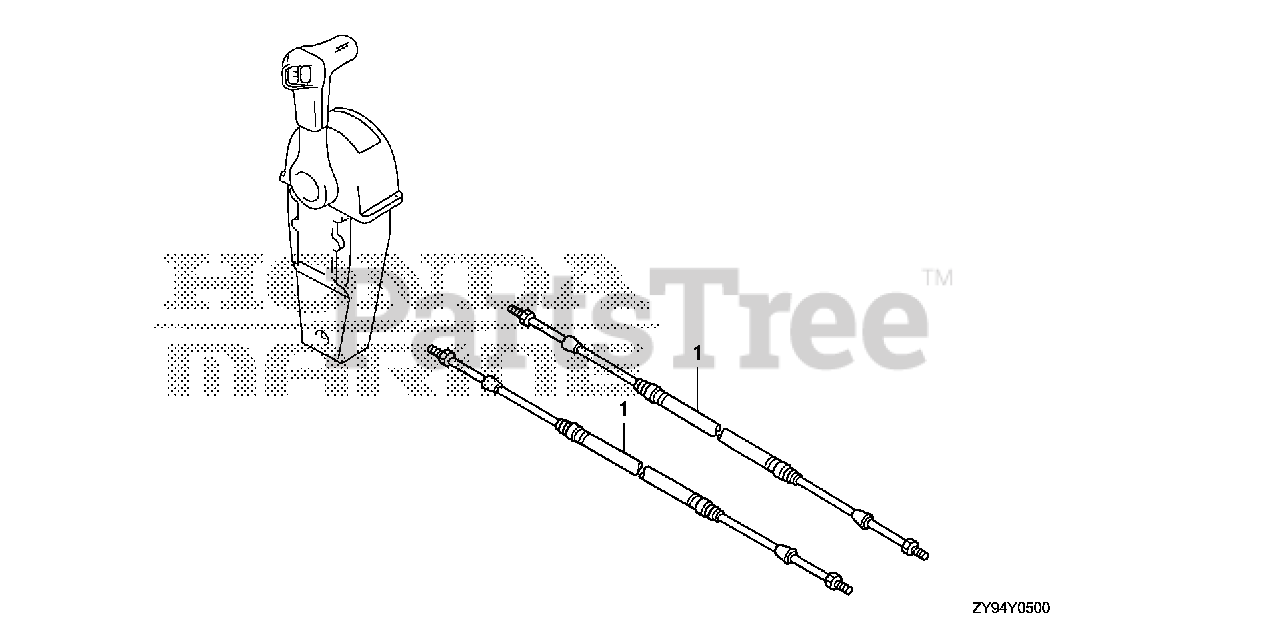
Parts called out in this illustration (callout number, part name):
1	CABLE, REMOTE CONTROL (10'') (LOW FRICTION)
1	CABLE ASSY., PUSH-PULL (33C-5FT)
1	CABLE, REMOTE CONTROL (11'') (LOW FRICTION)
1	CABLE ASSY., PUSH-PULL (33C-6FT)
1	CABLE, REMOTE CONTROL (12'') (LOW FRICTION)
1	CABLE ASSY., PUSH-PULL (33C-7FT)
1	CABLE, REMOTE CONTROL (13'') (LOW FRICTION)
1	CABLE ASSY., PUSH-PULL (33C-8FT)
1	CABLE, REMOTE CONTROL (14'') (LOW FRICTION)
1	CABLE ASSY., PUSH-PULL (33C-9F T)
1	CABLE, REMOTE CONTROL (15'') (LOW FRICTION)
1	CABLE ASSY., PUSH-PULL (33C-10FT)
1	CABLE, REMOTE CONTROL (16'') (LOW FRICTION) (NOT AVAILABLE)
1	CABLE ASSY., PUSH-PULL (33C-11FT)
1	CABLE, REMOTE CONTROL (17'') (LOW FRICTION)
1	CABLE ASSY., PUSH-PULL (33C-12 FT)
1	CABLE, REMOTE CONTROL (18') (LOW FRICTION) (NOT AVAILABLE)
1	CABLE ASSY., PUSH-PULL (33C-13 FT)
1	CABLE, REMOTE CONTROL (1 9'') (LOW FRICTION)
1	CABLE ASSY., PUSH-PULL (33C-14FT)
1	CABLE, REMOTE CONTROL (20'') (LOW FRICTION) (NOT AVAILABLE)
1	CABLE ASSY., PUSH-PULL (33C-15 FT)
1	CABLE, REMOTE CONTROL (21') (LOW FRICTION)
1	CABLE ASSY., PUSH-PULL (33C-16FT)
1	CABLE, REMOTE CONTROL (22') (LOW FRICTION) (NOT AVAILABLE)
1	CABLE ASSY., PUSH-PULL (33C-17 FT)
1	CABLE, REMOTE CONTROL (2 3'') (LOW FRICTION)
1	CABLE ASSY., PUSH-PULL (33C-18 FT)
1	CABLE, REMOTE CONTROL (24') (LOW FRICTION) (NOT AVAILABLE)
1	CABLE ASSY., PUSH-PULL (33C-19FT)
1	CABLE, REMOTE CONTROL (25') (LOW FRICTION)
1	CABLE ASSY., PUSH-PULL (33C-20FT)
1	CABLE, REMOTE CONTROL (26') (LOW FRICTION)
1	CABLE ASSY., PUSH-PULL (33C-21FT)
1	CABLE, REMOTE CONTROL (27') (LOW FRICTION)
1	CABLE ASSY., PUSH-PULL (33C-22FT)
1	CABLE, REMOTE CONTROL (28') (LOW FRICTION) (NOT AVAILABLE)
1	CABLE ASSY., PUSH-PULL (33C-23FT)
1	CABLE, REMOTE CONTROL (2 9') (LOW FRICTION)
1	CABLE ASSY., PUSH-PULL (33C-24FT)
1	CABLE, REMOTE CONTROL (30') (LOW FRICTION) (NOT AVAILABLE)
1	CABLE ASSY., PUSH-PULL (33C-25FT)
1	CABLE, REMOTE CONTROL (31') (LOW FRICTION)
1	CABLE ASSY., PUSH-PULL (33C-26FT)
1	CABLE, REMOTE CONTROL (32') (LOW FRICTION) (NOT AVAILABLE)
1	CABLE ASSY., PUSH-PULL (33C-27FT)
1	CABLE, REMOTE CONTROL (33') (LOW FRICTION)
1	CABLE ASSY., PUSH-PULL (33C-28FT)
1	CABLE, REMOTE CONTROL (34') (LOW FRICTION)
1	CABLE ASSY., PUSH-PULL (33C-29FT)
1	CABLE, REMOTE CONTROL (35') (LOW FRICTION)
1	CABLE ASSY., PUSH-PULL (33C-30FT)
1	CABLE ASSY., PUSH-PULL (33C-31FT)
1	CABLE ASSY., PUSH-PULL (33C-32FT)
